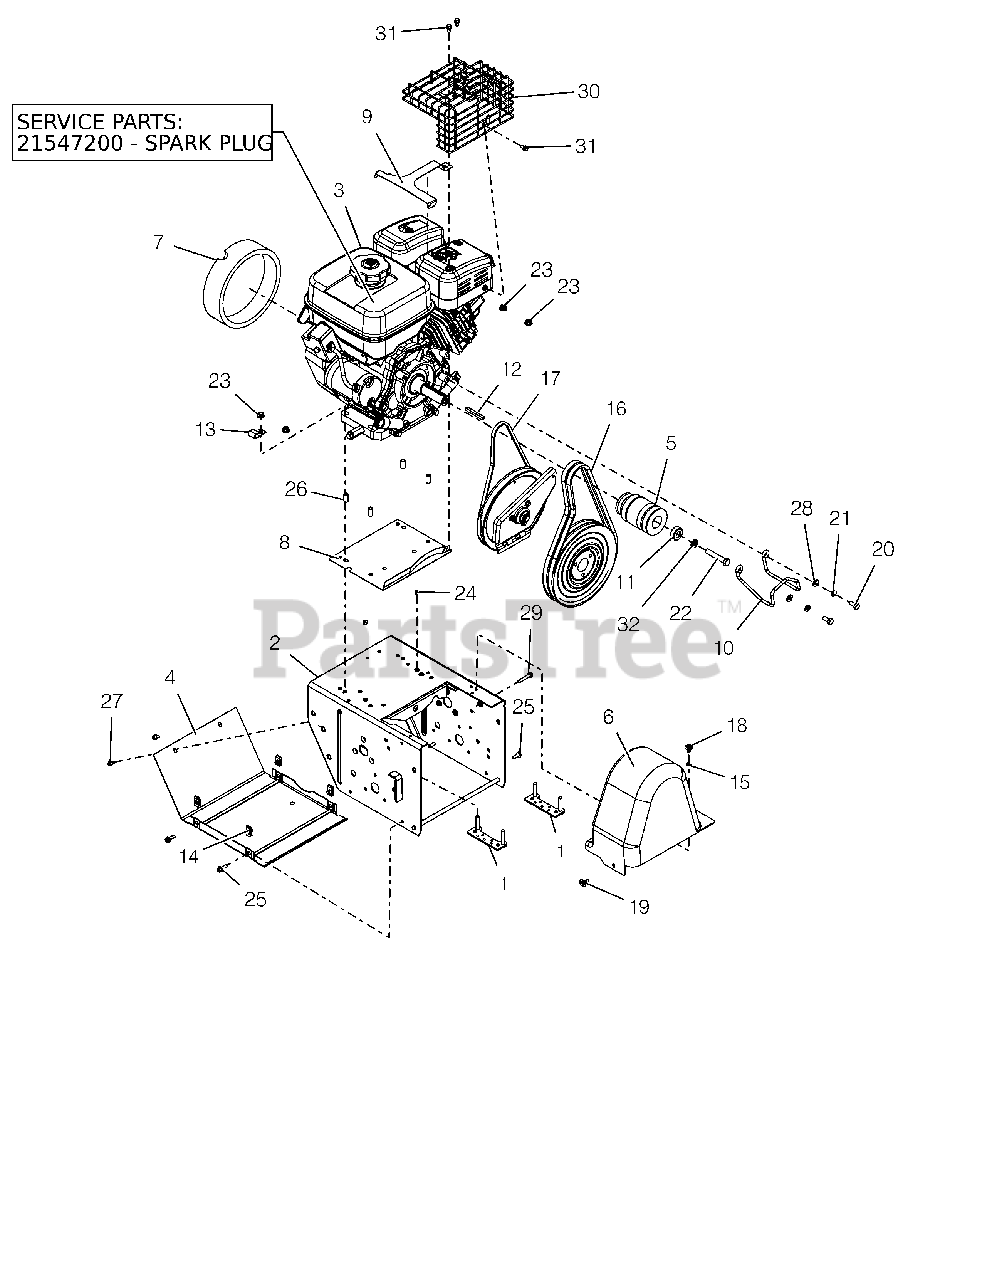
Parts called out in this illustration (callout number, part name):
1	STRAP, ENGINE BOLT-LARGE BRIGG
2	FRAME, MAIN - PRO (WELDMENT)
3	ENGINE,SUBARU EX27 AS 120V
3	PLUG, SPARK SUBARU
4	COVER, BOTTOM
5	SHEAVE, SUBARU EX27
6	COVER, BELT-TALL PRO
7	FOAM COVER, RECOIL-SUBARU
8	BAFFLE, WATER - LARGE BLOCK
9	GUARD, SNOW-SUBARU
10	FINGER, BELT
11	BSHG-SPACER .47X1.25X.50
12	KEY .25X.25X2.25
14	NUT-RTNR .25-20X.56
15	NUT-PUSH .25X.50 O.D.
16	V-BELT, HA-RAW EDGE (SET)
17	V-BELT, 3L-RAW EDGE
18	SCR-TAP .25-20X.50 LGHWH TR YZ
19	SCR-TAP .25-20X.5 CAPTIVE
20	BLT-HEX .31-24X.75 YWZC GR5
21	WSHR-LK .312X.097 HVY YWZC
22	BLT-HEX .44-20X2.50 GR5 YWZC
23	@NUT-LK-CTR-FLG .31-18 YZ GR F
24	RVT-POP .187 YZ
25	BLT-HEX .25-20X.75 HWH YZ GR5
26	BSHG-SLV .325X.400X.795
27	SCR-TAP .25-20X.50 HWH TR YWZ
28	@WSHR-FL-STL.344X.688X.065YWZC
29	@SCR-TAP .25-20X1.50 HWH TR YZ
30	MUFFLER GUARD, SUBARU EX27
31	BLT-SERHFWH M6X1.0X12 8.8 CZ
32	@WSHR-LK .44X.109 REG YWZC
